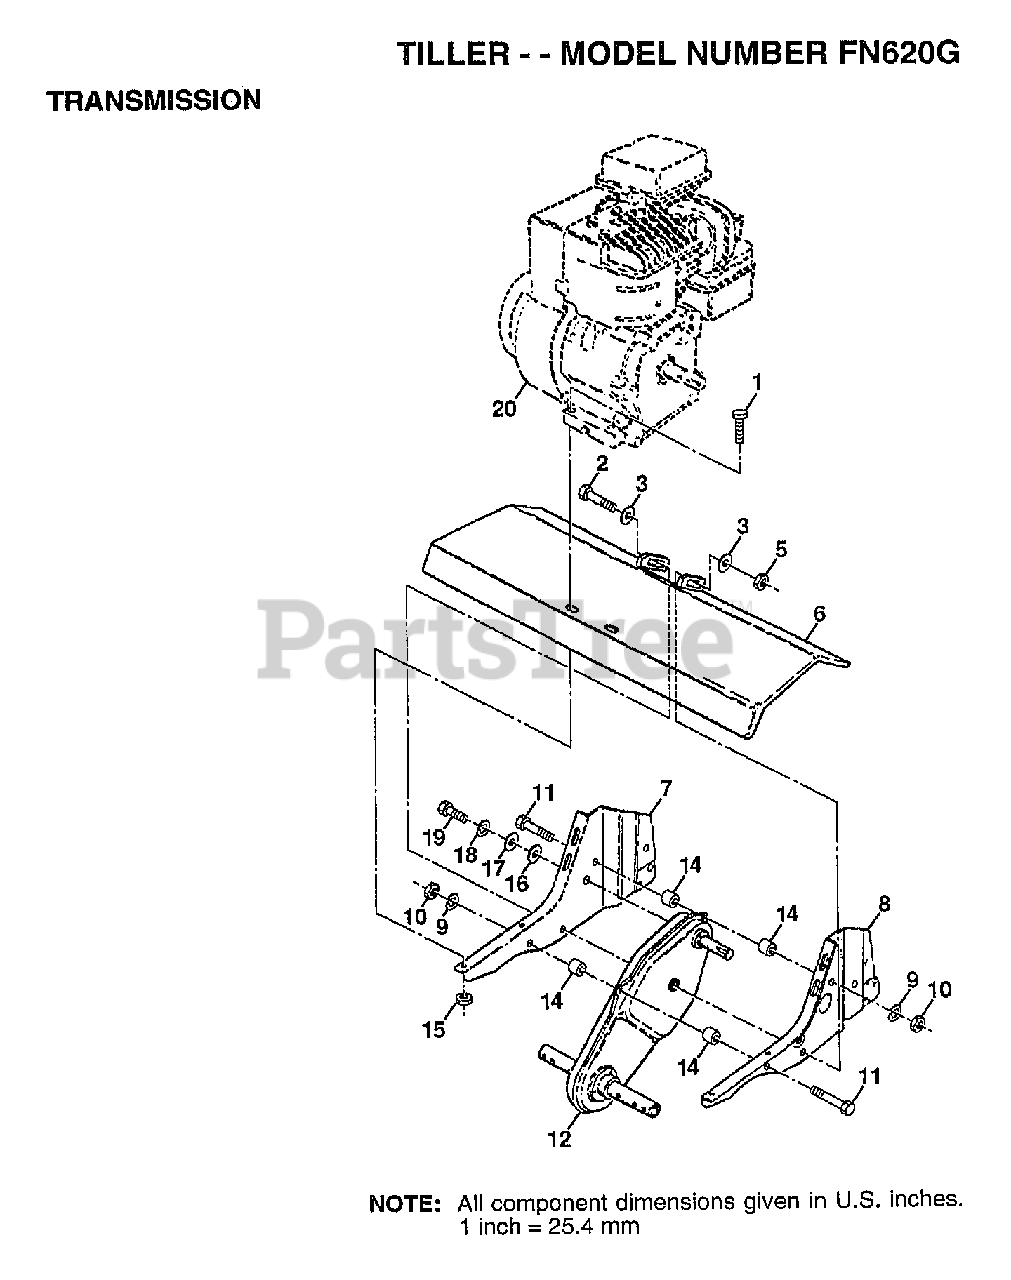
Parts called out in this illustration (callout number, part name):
1	BOLT.HEX.5/16-1.5
2	BOLT HEX 3/8-16
3	WASHER
5	NUT
6	"SHIELD, TINE"
7	BRACKET.ENGINE.RH
8	BRKT.ENGINE.LH
9	LOCKWASHER
10	NUT.HEX.5/16-18
14	SPLIT SPACER RT
16	WASHER
17	WASHER
18	LOCKWASHER
19	BOLT
